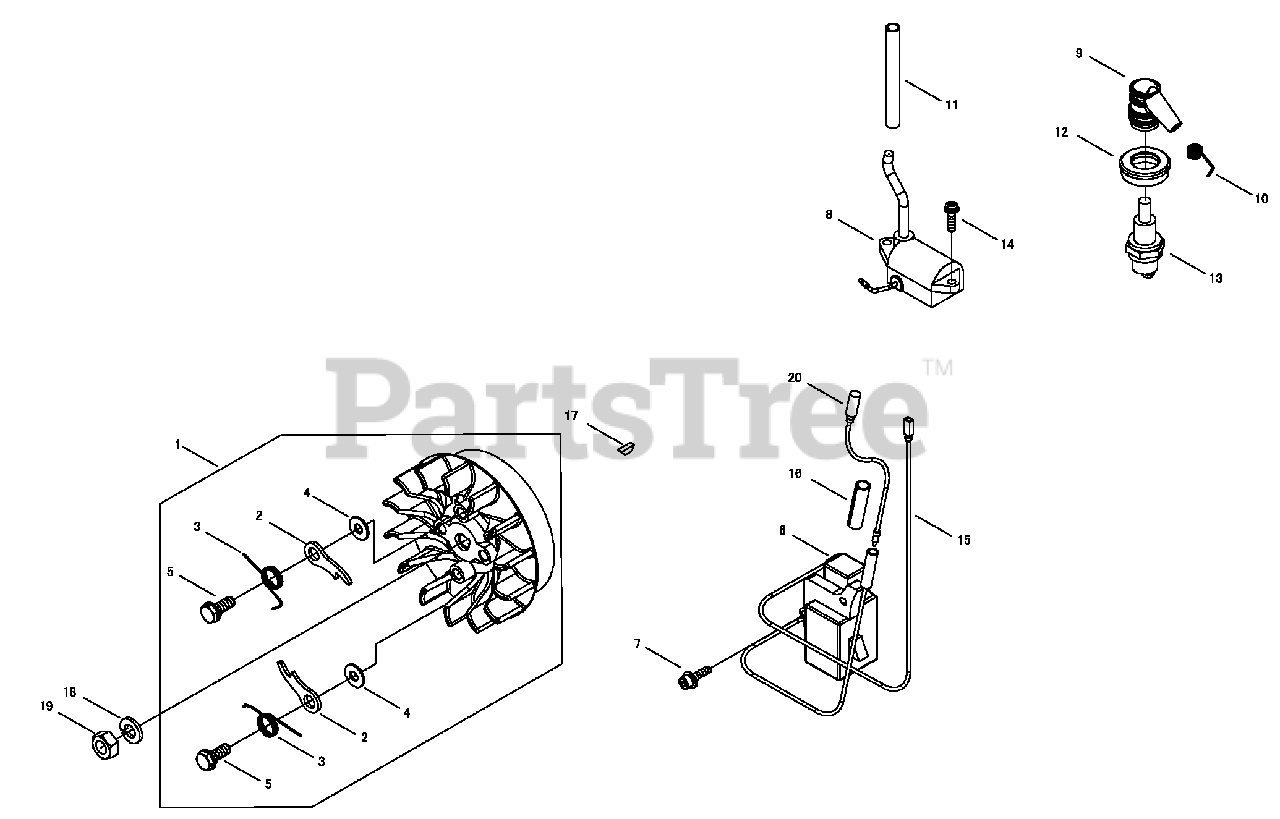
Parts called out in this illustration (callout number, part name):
1	FLYWHEEL
2	RATCHET
3	SPRING, RATCHET
4	WASHER 6 MM
5	BOLT
6	COIL, EXCITER
7	BOLT M4×20
8	COIL, IGNITION
9	CAP, SPARK PLUG
10	TERMINAL, SPARK PLUG
11	TUBE
12	SEAL, SPARK PLUG
13	SPARK PLUG - BPMR7A
14	SCREW M4×16
15	WIRE
16	TUBE
17	KEY, WOODRUFF 3×10
18	WASHER, SPRING 8
19	NUT
20	WIRE
